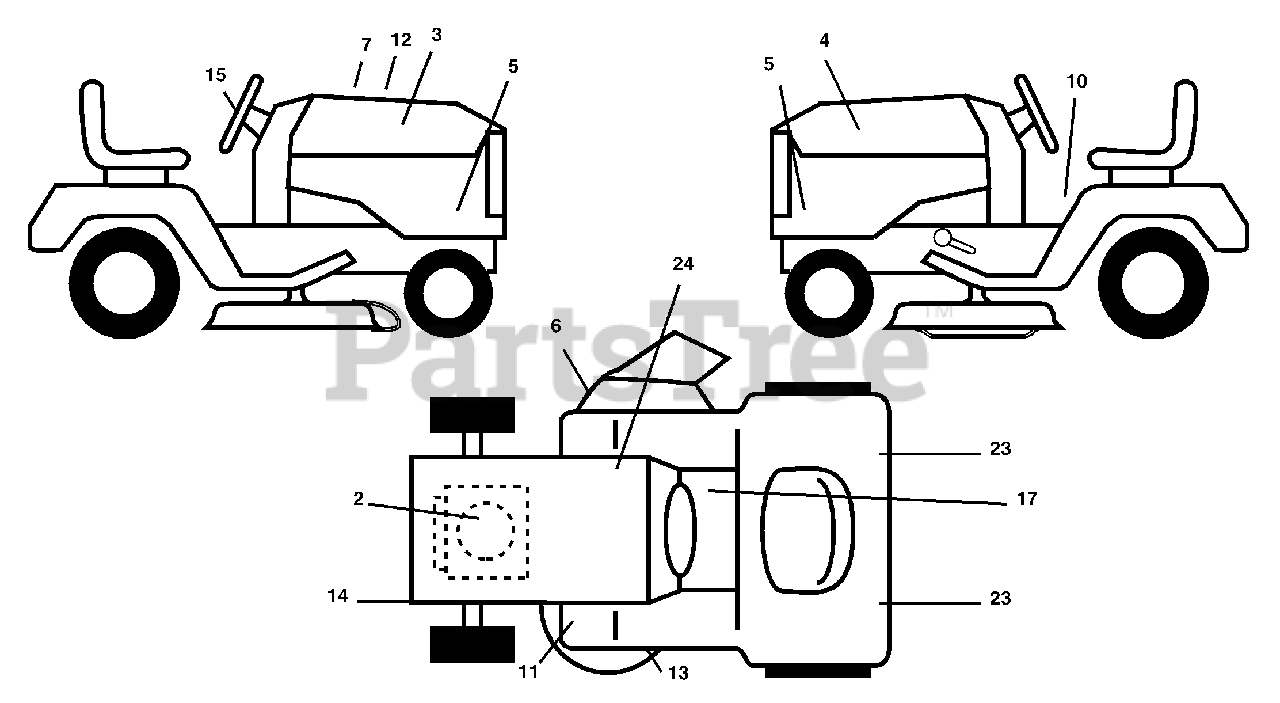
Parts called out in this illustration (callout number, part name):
1	Decal, Deck heavy Duty
2	Decal, Engine
3	Decal, Hood, RH
4	Decal, Hood, LH
5	Decal, Side Panel
6	Decal, Warning
7	Decal, Customer Resp.
10	Decal, Danger
11	Decal, Foot Rest
12	Decal, Replacement
13	Decal, V-Belt Sch
14	Decal, Caution
15	Decal, Ins. Strg Whl
17	Decal, Saddle Brake Parking
23	Reflector, Taillight
24	Decal, Btry Dngr/Psn
